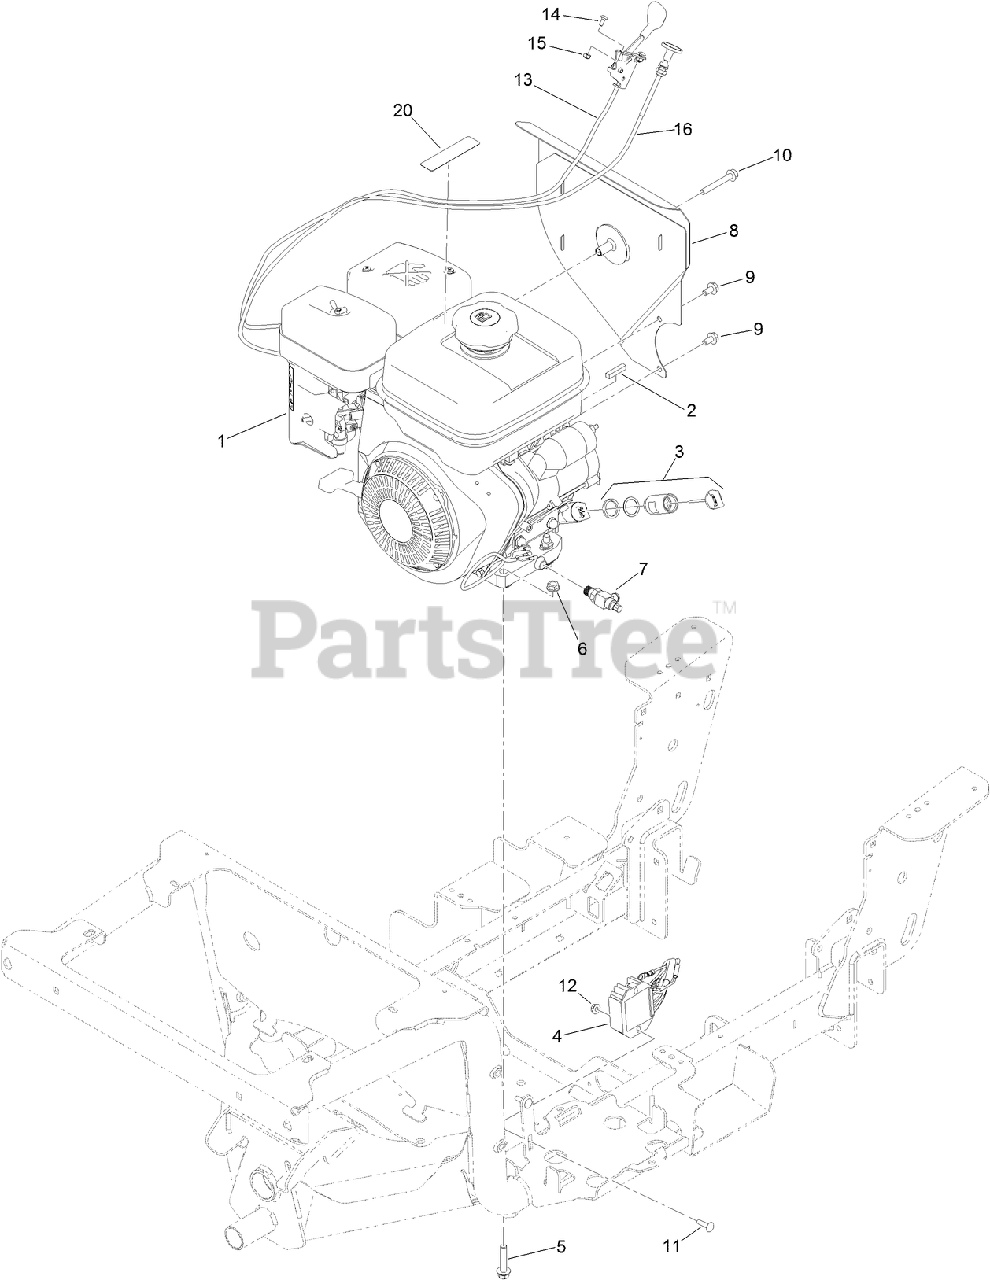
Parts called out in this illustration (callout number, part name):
2	KEY-CRANKSHAFT
3	EXTENDER-DIPSTICK
4	REGULATOR
5	SCREW-HHF
6	NUT-HF
7	Valve-Oil Drain
8	HEAT SHIELD ASM
9	SCREW-HHF, LOCK
10	SCREW-HHF
11	SCREW-CARR
12	NUT-HF
13	CONTROL-THROTTLE
14	BOLT-CARR
15	NUT-LOCK, NI
16	CABLE-CHOKE, PUSH/PULL
20	DECAL-ARRESTER, SPARK
